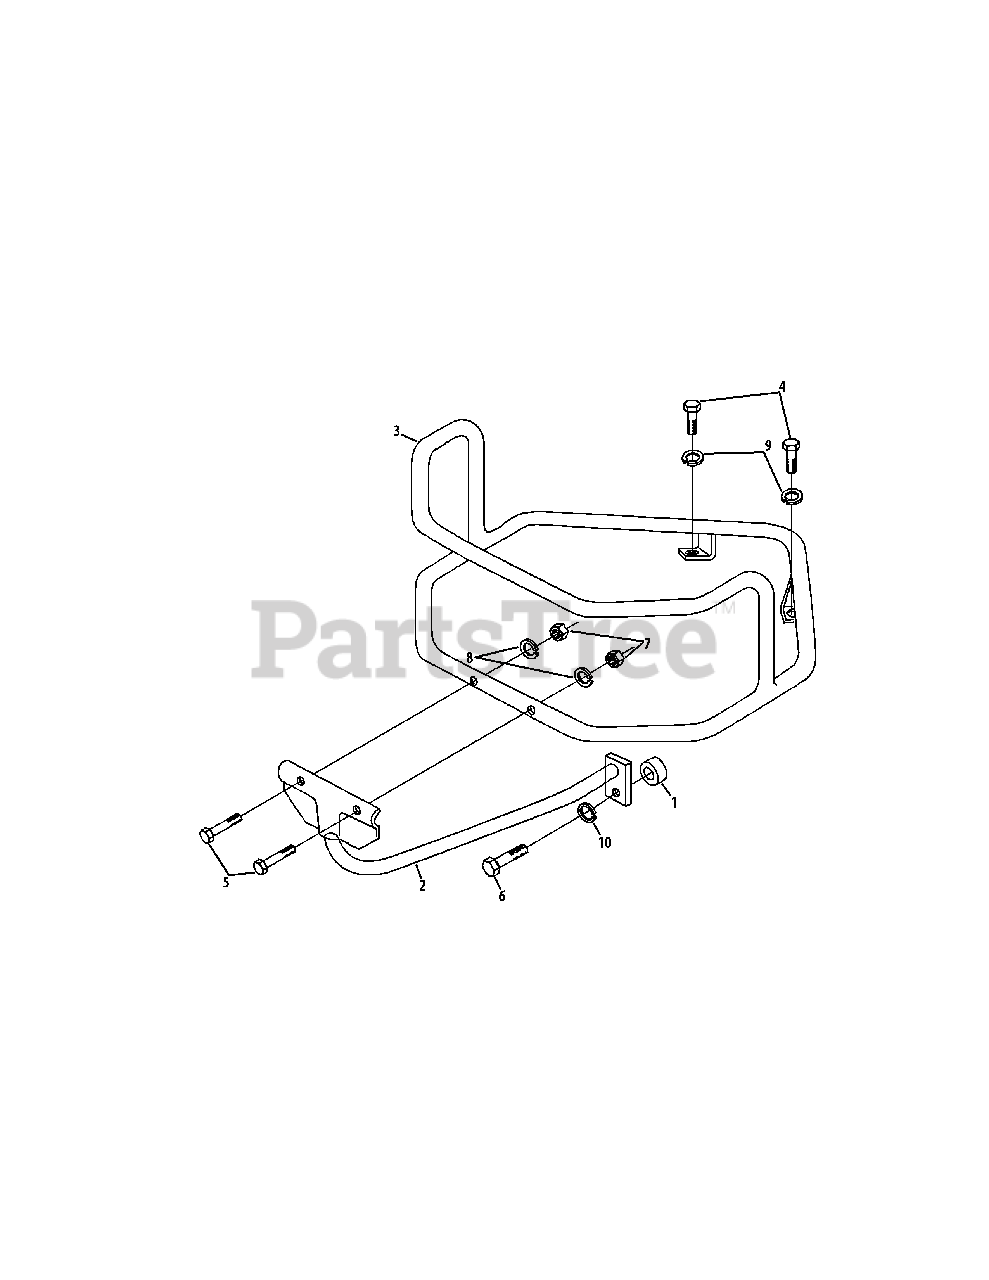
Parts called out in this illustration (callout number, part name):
1	Spacer, 1.0 x .546 x .5
2	Bottom Bumper Brace
3	Bumper Guard
4	Hex Screw, 3/8"-16 x 1.00
5	Hex Screw, 5/16"-18 x 1.50
6	Hex Screw, 1/2"-13 x 1.50
7	Hex Nut, 5/16"-18
8	Lock Washer, 5/16"
9	Lock Washer, 3/8"
10	Lock Washer, 1/2"
